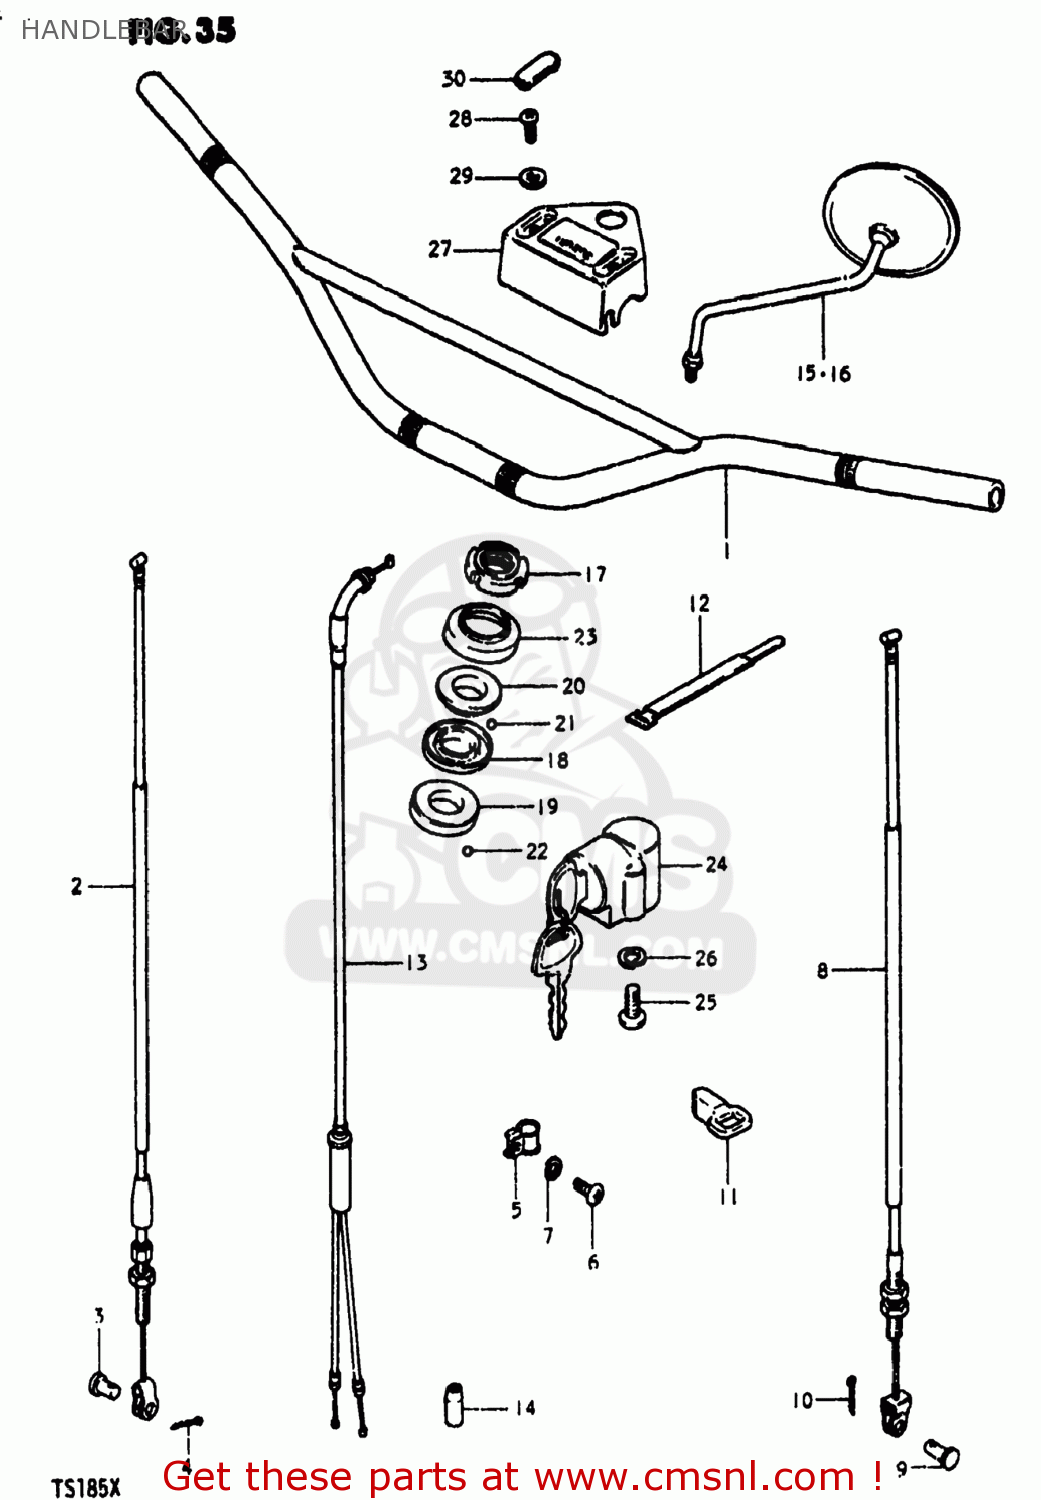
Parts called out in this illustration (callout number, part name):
1	HANDLEBAR
2	CABLE,FRONT BRAKE
3	PIN(L:13.5)
4	PIN
5	GUIDE,CABLE
6	SCREW
7	LOCK WASHER
8	CABLE ASSEMBLY,CLUTCH
9	PIN(L:15)
10	PIN
11	GUIDE,CLUTCH CABLE
12	CLAMP
13	CABLE ASSEMBLY,THROTTLE
14	SEAL,DUST(7X18X30)
15	MIRROR ASSEMBLY,RIGHT
16	MIRROR ASSEMBLY,LEFT
17	NUT,STEERING STEM(25X44X10)
18	RACE,STEERING INNER UPR
19	LACE,STEERING INNER LWR
20	RACE,STEERING OUTER UPR
21	BALL
22	BALL
23	DUST SEAL,STEERING UPR
24	LOCK ASSEMBLY,STEERING
25	SCREW
26	LOCK WASHER
27	COVER,STEERING HEAD
28	SCREW 6X12
29	WASHER
30	CAP,PILOT BOX BOLT
